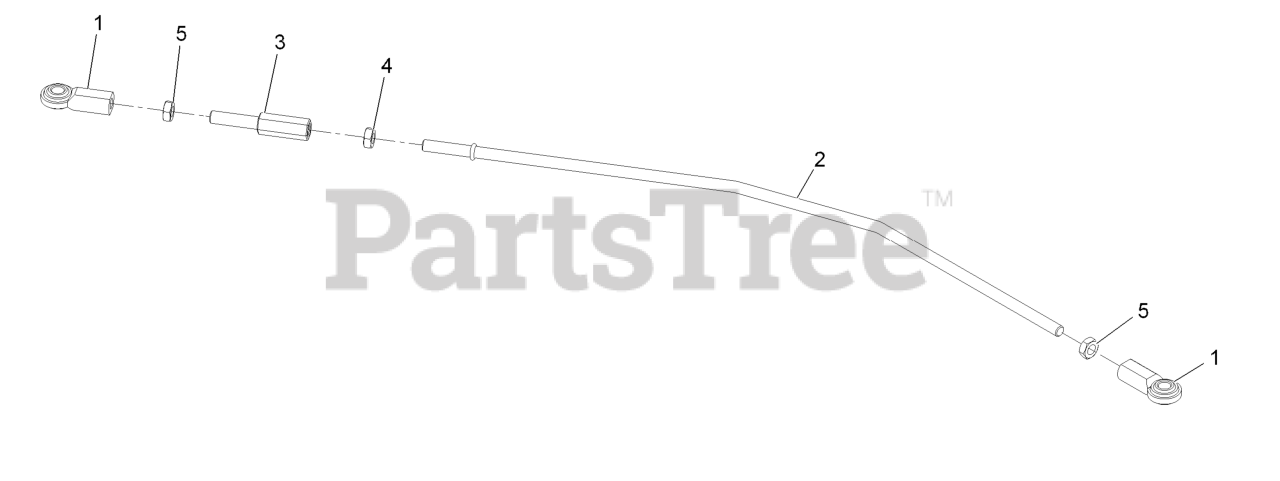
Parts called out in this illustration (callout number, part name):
1	Balljoint
2	Link-Lower,Motion Control
3	Rod-Adjustment
4	Nut-Jam 3/8-24 LH
5	Nut-Jam 3/8-24
